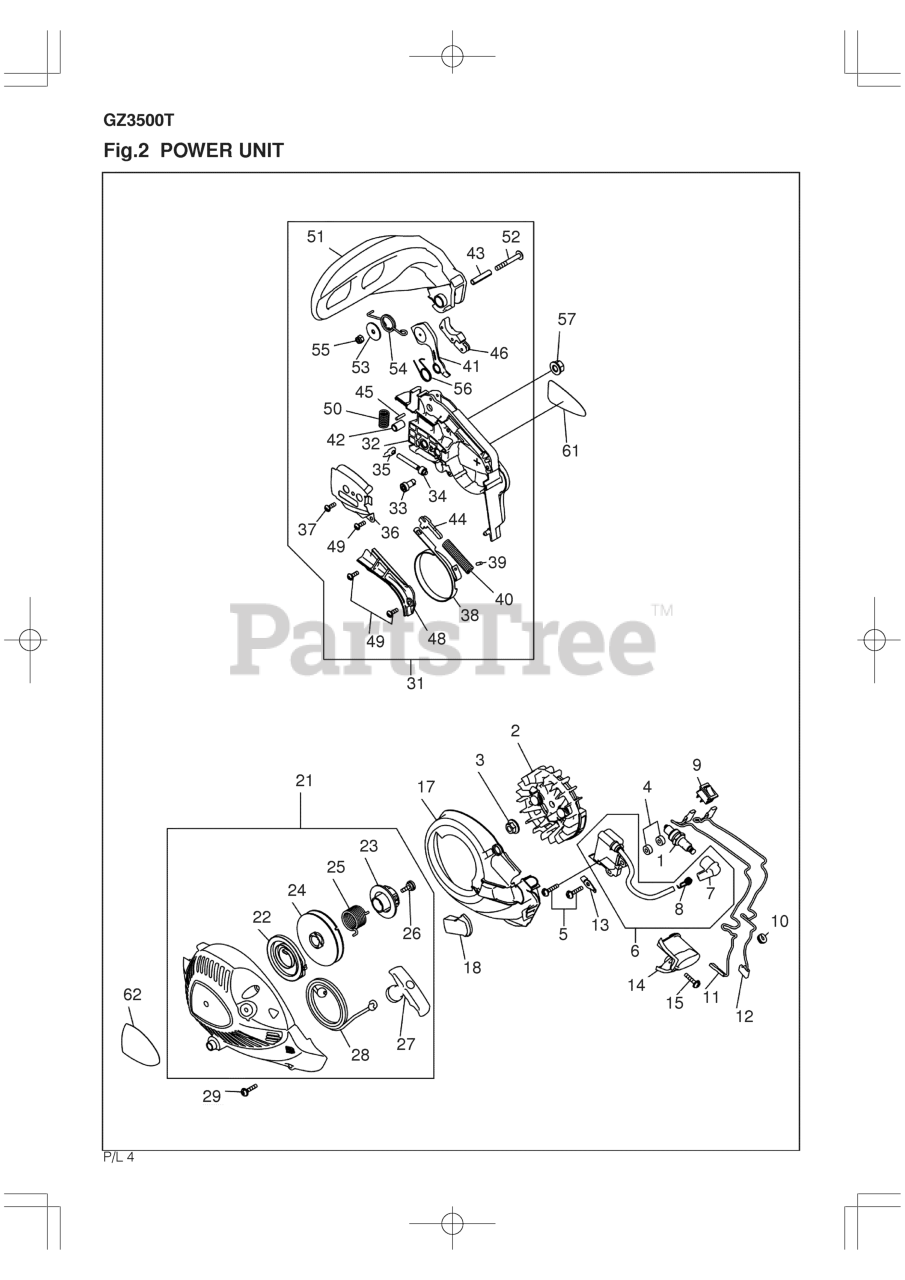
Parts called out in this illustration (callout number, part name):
1	SPARK PLUG
2	ROTOR ASSY
3	NUT
5	BOLT TORX 09
6	COIL COMP
9	SWITCH ASSEMBLY
10	GROMMET
11	CORD, SWITCH
12	CORD, EARTH
13	TERMINAL
14	COVER, PLUG
15	CORD, FAN
18	GUIDE, DF
21	RECOIL ASSY
22	SPRING ASSY
23	CAM, PLATE
24	REEL
25	SPRING
26	SCREW
27	KNOB
28	ROPE
29	SCREW
31	BRAKE ASSY
32	COVER, CHAIN
33	GEAR
34	SCREW
35	NUT
36	PLATE
37	SCREW
39	ROLLER
45	ROLLER
46	LEVER, BRAKE COMPLETE
48	COVER, BRAKE
49	SCREW
50	SPRING
51	GUARD
54	SPRING, RETURN
55	NUT
56	SPRING
57	NUT
61	LABEL, COVER
62	LABEL, RECOIL
